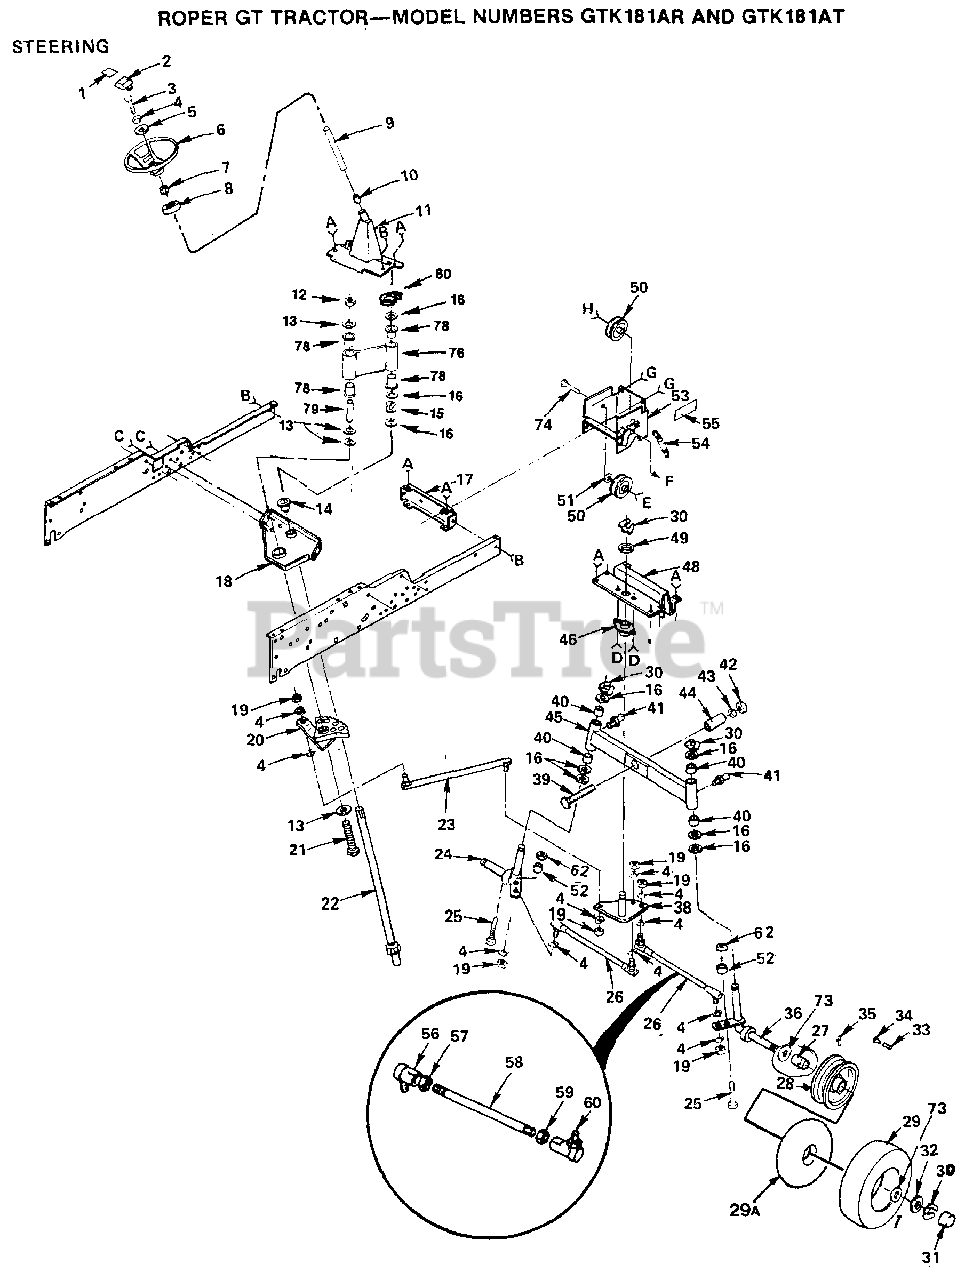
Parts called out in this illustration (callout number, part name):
1	DECAL - STEERING WHEEL
2	INSERT-WHEEL LT
3	BOLT
4	LOCKWASHER
5	WASHER T
7	ADAPTER LT
9	TUBE
10	"T, BEARING"
11	SUPPORT ASSY T
12	NUT LTV
13	WASHER GT
14	"FLANGE GT, BEAR."
15	KLIP RING
16	WASHER .T
17	FRAME BRACKET GT
20	SECTOR T
21	BOLT T
22	SHAFT STEERING GT
23	LINK.DRAG.T
24	SPINDLE ASSY T
25	BOLT, HEX 3/8 - 16 X 2
26	TIE ROD T
27	"FLANGE, BEARING"
29A	TUBE.16X6.5/7.5-8
31	HUB CAP
33	VALVE CAP
34	VALVE STEM LT
35	FITTING LT
36	SPINDLE RH T
38	"T, BELLCRANK"
39	BOLT
40	BRNG. T
41	ZERK M
42	NUT X
43	WASHER
45	AXLE ASSEMBLY
48	AXLE BRACKET T
49	WASHER
50	IDLER-INSIDE T
51	WASHER T
53	IDLER BRKT T
54	SPRING
57	NUT
59	NUT
73	WASHER 25/32 X 1-5/8 X 16 GA.
78	NYLINER T
79	TUBE T
